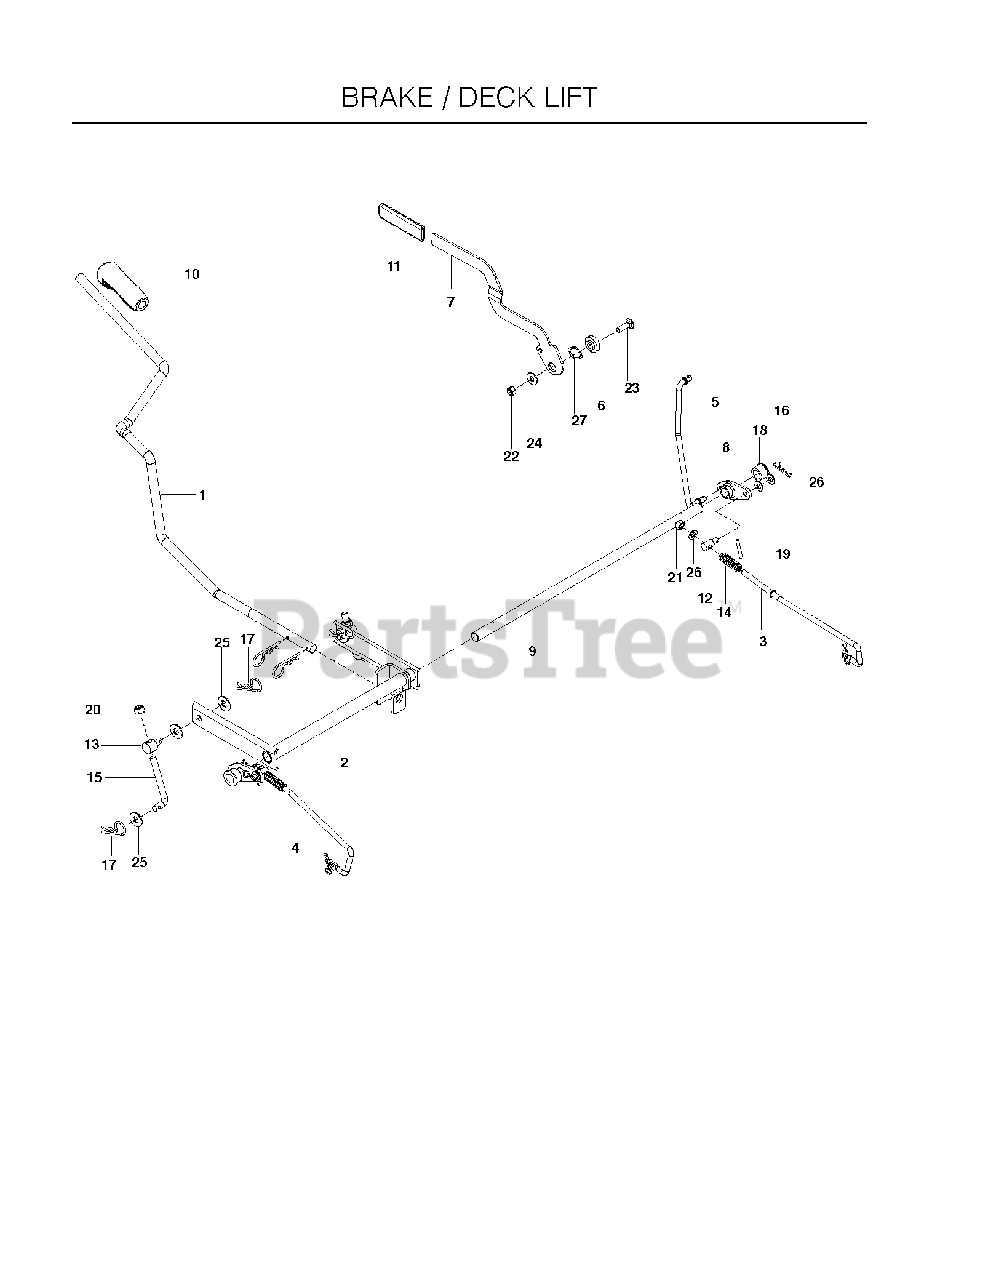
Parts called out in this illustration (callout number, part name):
1	ARM, LIFT HANDLE, BLK
2	WLDMT.LIFT.SHAFT.BLACK
3	LINKAGE, EZT BRAKE RT
4	LINKAGE, EZT BRAKE LT
5	LINKAGE, BRAKE, UPPER
6	BRAKE ARM PIVOT
7	HANDLE, BRAKE, BLK
8	BELLCRANK, BRAKE
9	ROD, BRAKE (2 2)
10	GRIP.LEVER.5625.ID
11	GRIP BRAKE HANDLE
12	BRAKE SWIVEL
16	HAIRPIN #2
17	HAIRPIN #4
18	PLASTIC BUSHING
19	ROLL PIN 3/16 X 1-1/4 ZD
20	NUT 3/8-16 NYLOC
21	NUT 5/16 NYLOC
22	NUT HEX 3/8-16 NYLON, THIN
23	RHSNB 3/8-16 X 1-1/4
24	WASHER, 7/16 DISC SPRING
25	RP WASHER 3/8 FLAT
26	FLAT WASHER 5/16 SAE
27	WASHER, .825 X 1.087, WAVE
